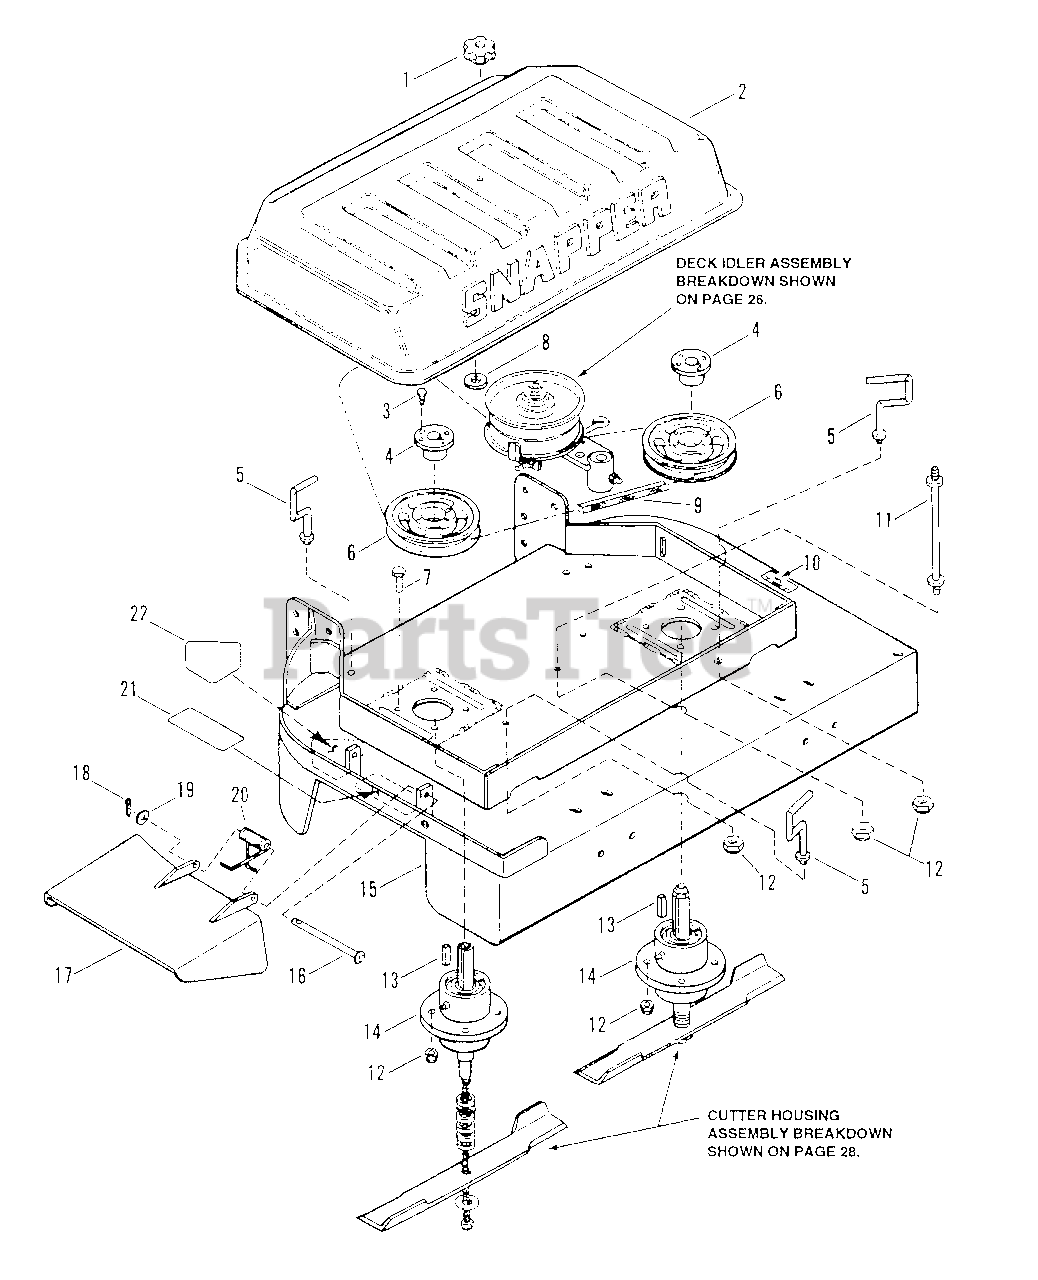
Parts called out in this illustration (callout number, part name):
1	KNOB, Hood
2	HOOD, 36" Silver
3	BOLT, 1/4 - 20 x 7/8" HHC
4	BUSHING, Taperlock
5	GUIDE, Belt
6	PULLEY, Single
7	SCREW, 3/8-16 x 1-1/4" Hex Head Cap
8	WASHER, 13/32 I.D. x 1-1/2" O.D.
9	BELT, 36" Deck
10	DECAL, Caution
11	STUD, Hood
12	NUT, 3/8 - 16 Nyloc
13	KEY, 1/4 x 1/4 x 2 1/2"
14	ASSEMBLY, Cutter Housing
15	DECK WELDMENT, 36"
16	ROD, Chute Pivot
17	DEFLECTOR, 36" Chute
18	COTTER PIN, 3/32 x 1"
19	WASHER, 5/16 SAE Flat
20	SPRING, Chute
21	DECAL, Caution
22	DECAL, Warning
